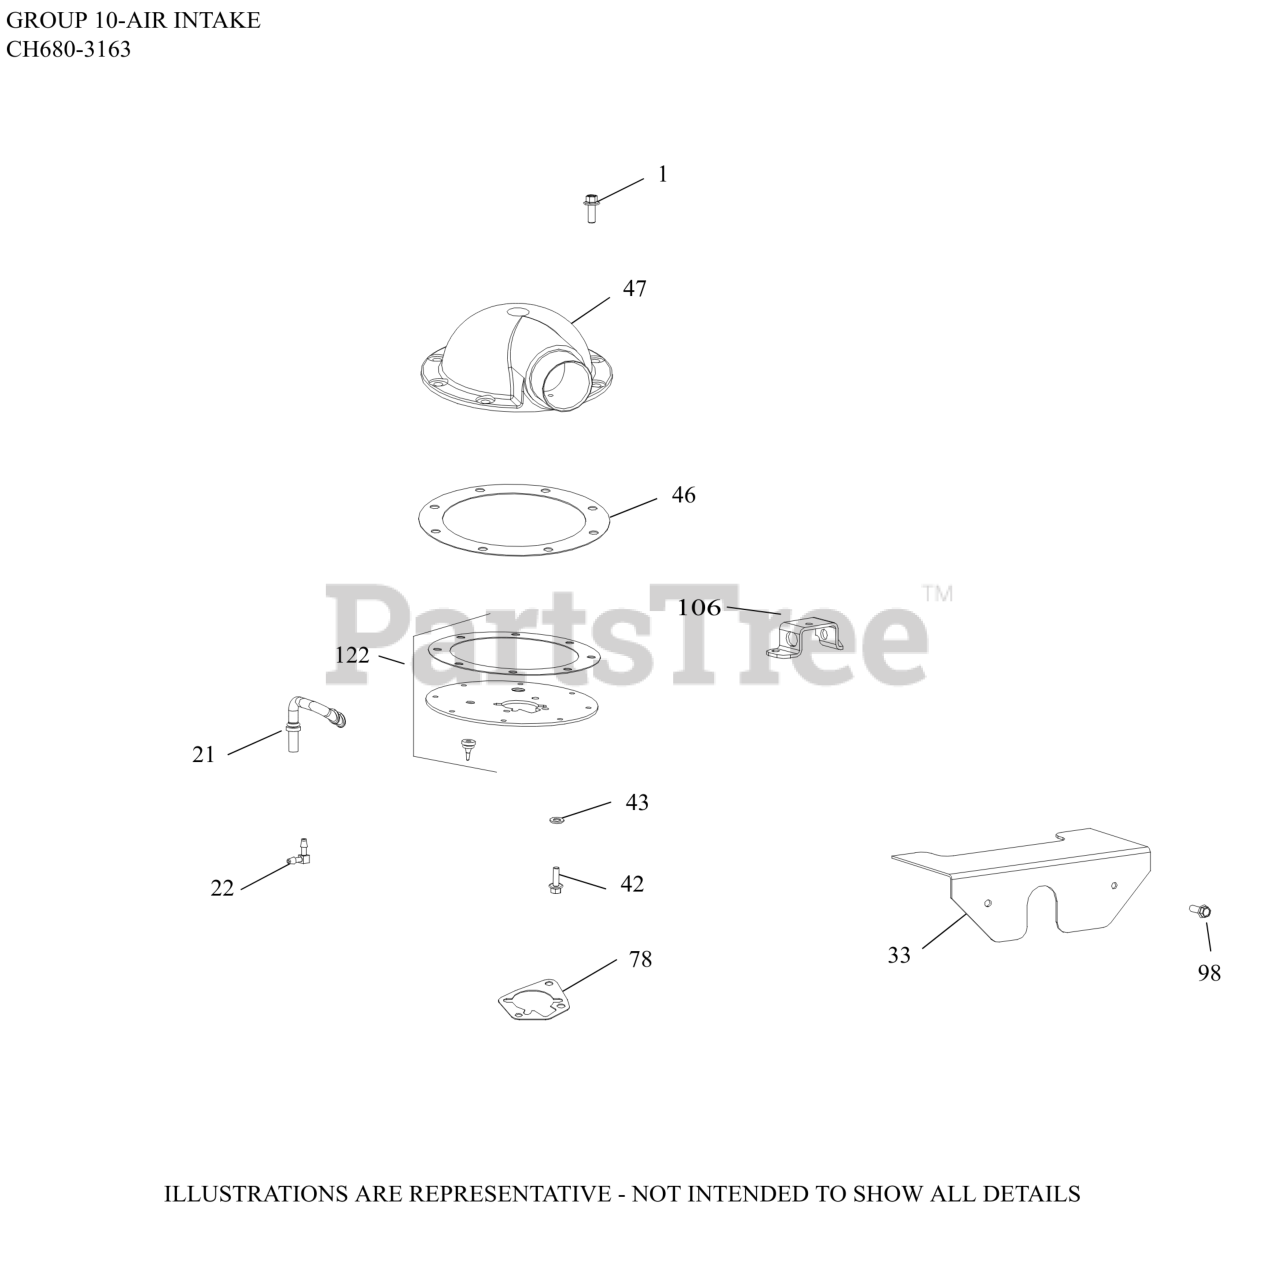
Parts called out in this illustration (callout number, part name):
1	SCREW, THREAD FORMING
1	SCREW, FLG M6X1.0X16
21	HOSE, EVAP
22	CONNECTOR, EVAPORATIVE HOSE
33	SHIELD, DEBRIS
42	SCREW, HVY FLG M5X.8X16
46	GASKET, AIR CLEANER ADAPTER
47	AIR INTAKE ADAPTER
78	GASKET, AIR CLEANER BASE
98	SCREW, HI-LOW
106	AIR CLEANER BRACKET
122	KIT, PLATE ADAPTER
NI	SCREW, HEX FLANGE
